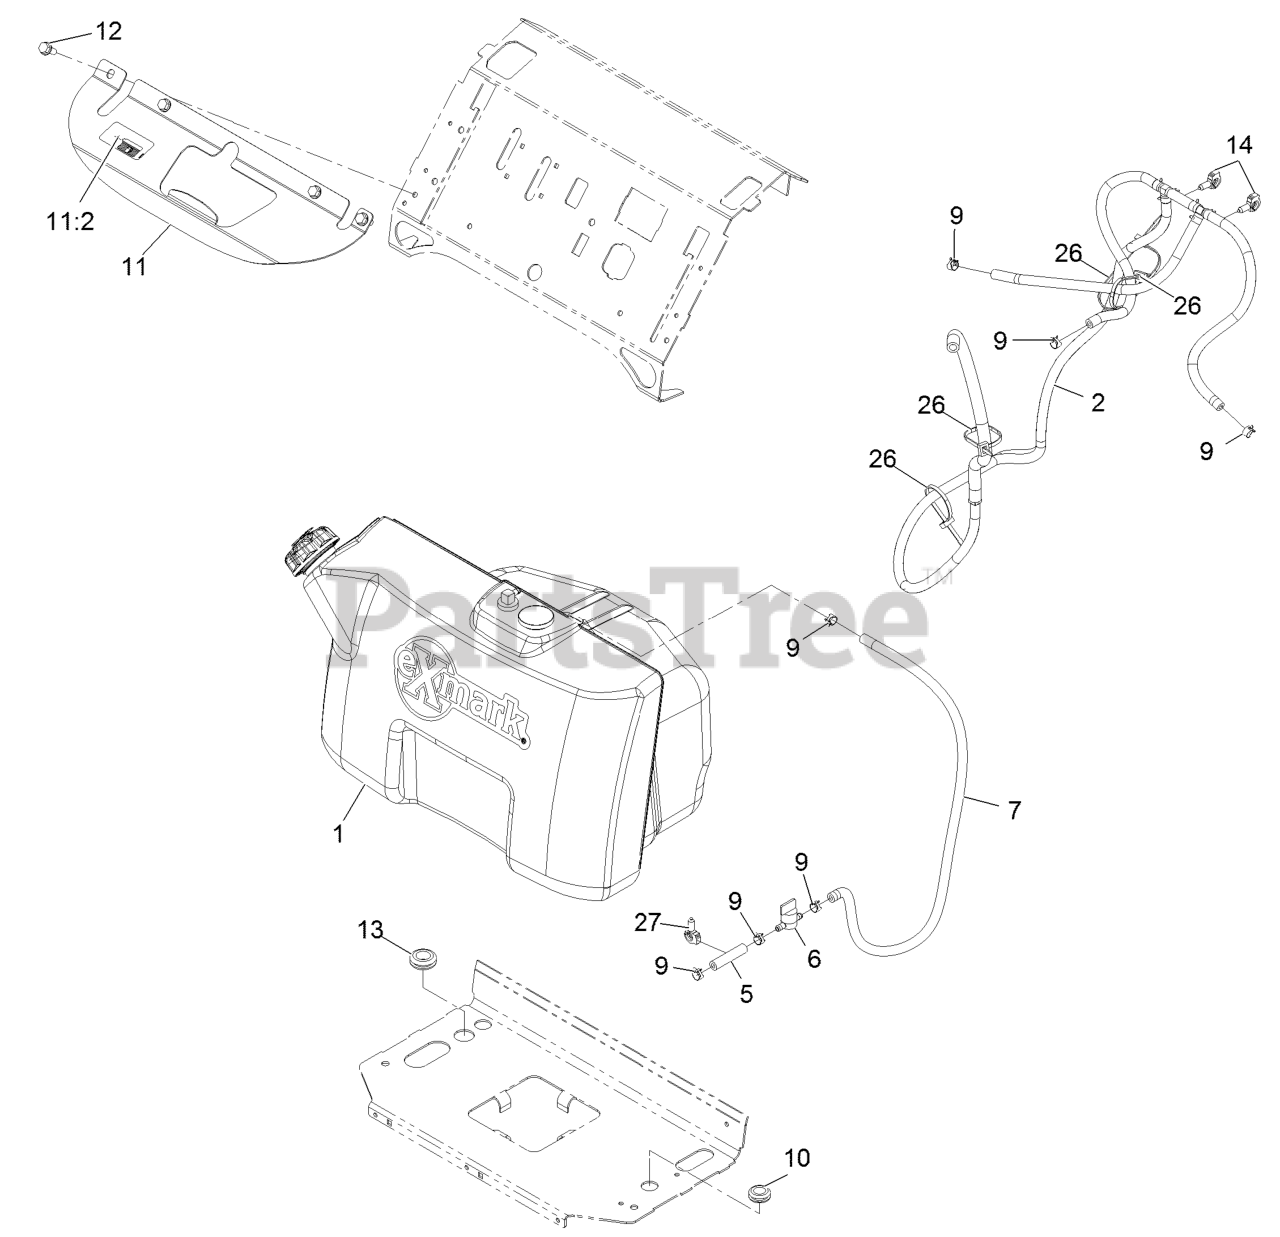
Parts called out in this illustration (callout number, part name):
2	VENT ASM
5	HOSE-FUEL
6	VALVE-FUEL
7	HOSE-FUEL
9	CLAMP-HOSE
10	GROMMET
11	BRACKET-TANK
11:2	DECAL-FILL, FUEL
12	SCREW-THD ROLL, HWH
13	GROMMET
14	CLIP-HARNESS
26	TIE-CABLE
27	CLIP-HARNESS
